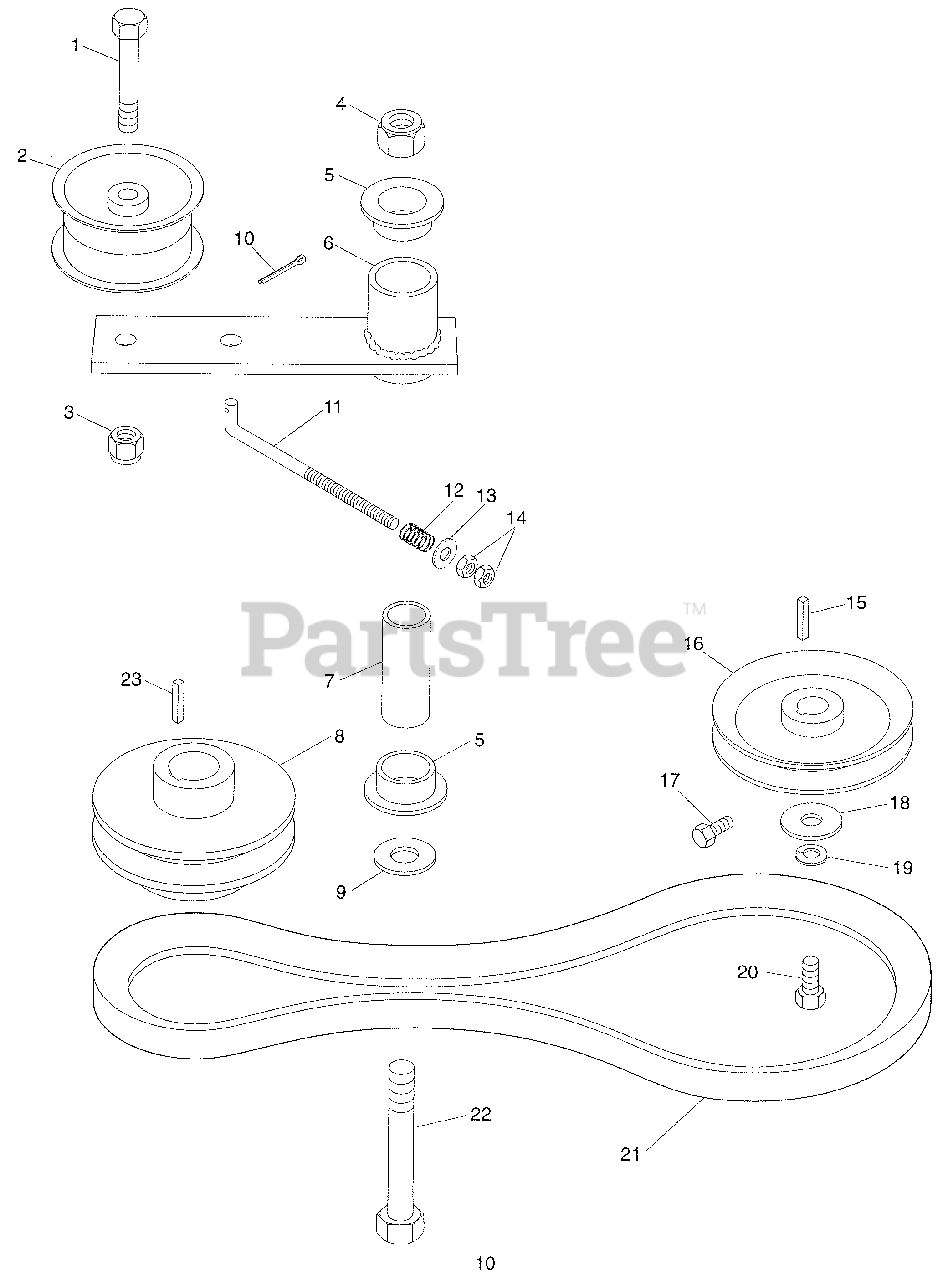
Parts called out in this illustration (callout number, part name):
1	Bolt Hex .38-16 X 1.75 Grade 5
2	Idler Pully Flat 3.25 X .625
3	Nut Locking Nylon .375-16 Grade 2
4	Nut Locking Nylon .50-13 Grade 2
5	Bushing Flange .762 X 1.0 X .580 X 1.48
6	Weldment, Ground Drive Idler
7	Bushing, Steel .560 X .745 X 2.04
8	Pulley-V 4.00 X 1.125 w/Key
9	Washer Flat Steel .531 X 1.062 X .095
10	Pin Cotter .09 X .75
11	Rod Idler 11.0 Large
12	Spring Compression .125 X .78 X 1.00
13	Washer Flat Steel .406 X .812 X .065
14	Nut Hex .375 X 24 Grade 2
15	Key Straight 5mm X 25mm X 5mm
16	Sheave, 4.0 X .199
17	Bolt Hex .25 X 20 X .50 Grade 5
18	Washer Flat Steel .281 X 1.250 X .062
19	Washer Lock .250 Regular
20	Bolt Hex M6 X 1.0 12 MM Large
21	V-Belt A-RMA 28.22 X 33/64
22	Bolt Hex .50-13 X 3.00
23	Key Square .25 X 1.00 .25
